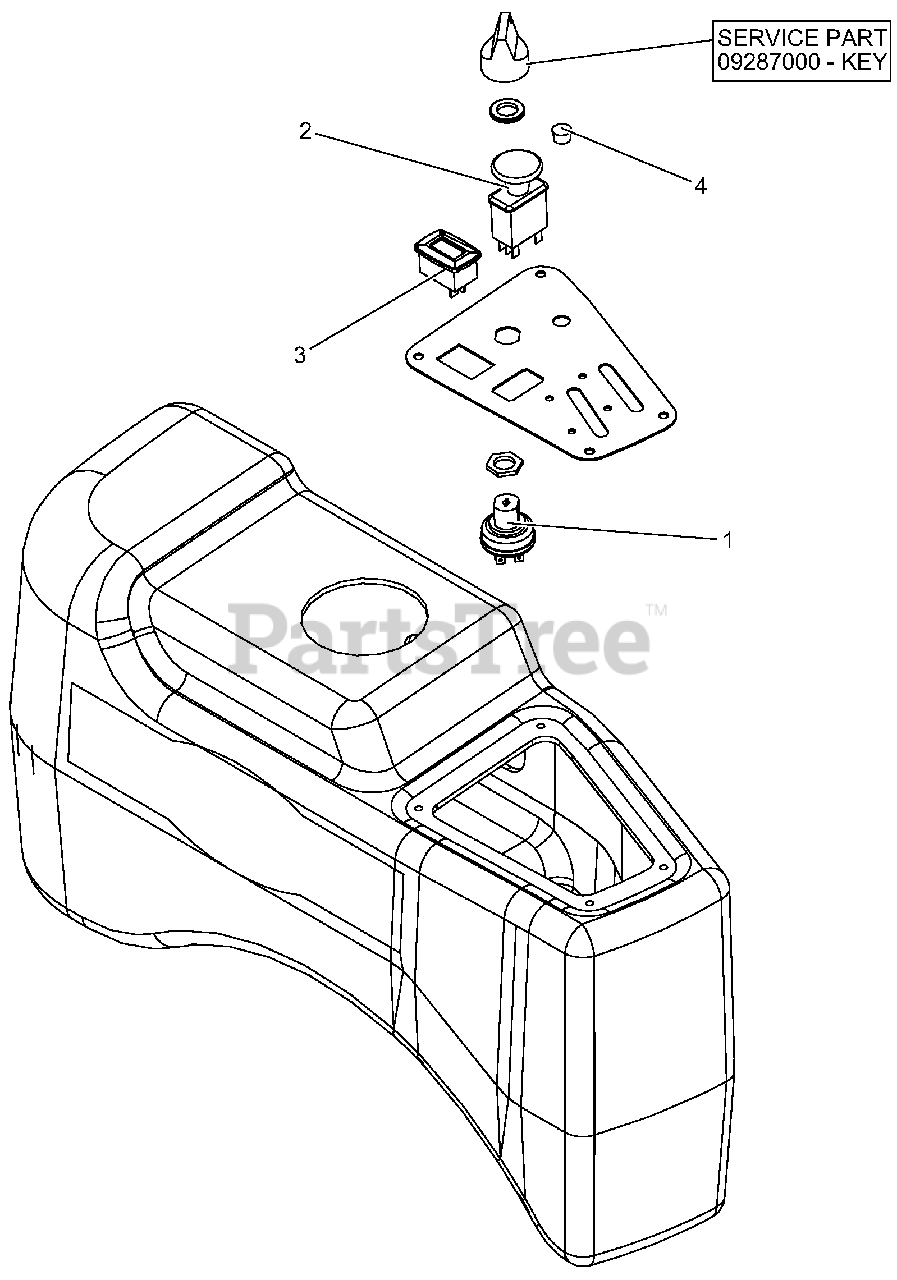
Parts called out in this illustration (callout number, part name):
1	SWITCH, IGNITION
2	SWITCH, CLUTCH
3	METER, HOUR W/MAINTENANCE
4	PLUG, HOLE .50 DIA
